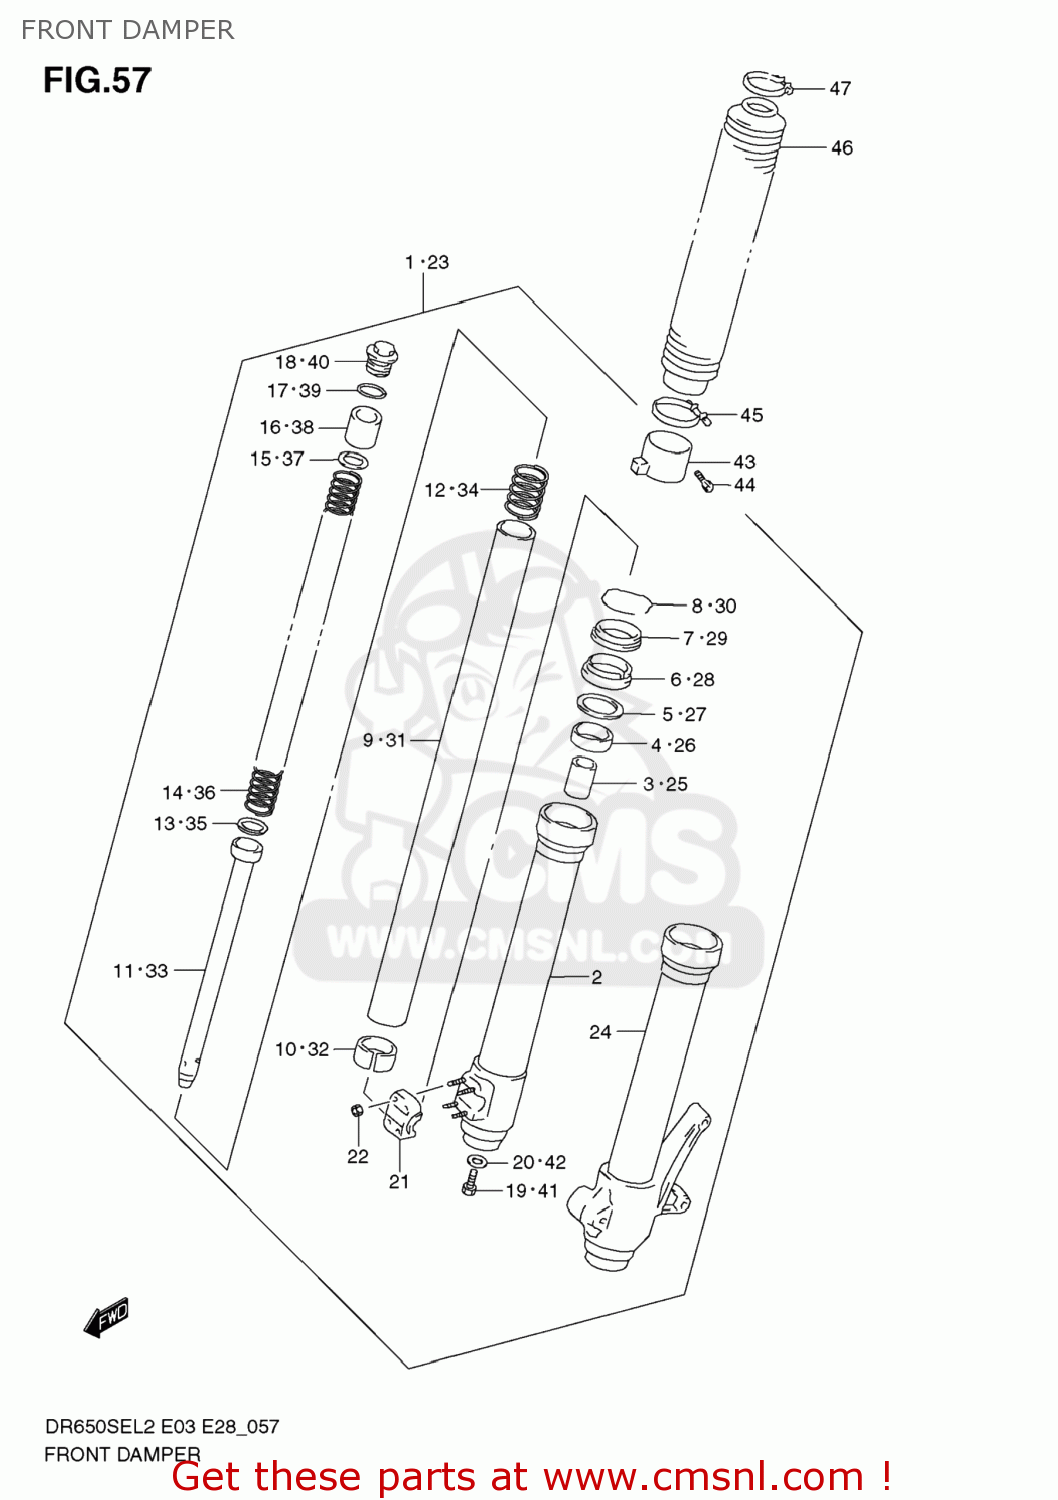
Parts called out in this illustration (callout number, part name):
1	DAMPER ASSY,FR FORK,R
2	TUBE,OUTER,R
3	PIECE,OIL LOCK
4	METAL,SLIDE
5	WASHER
6	SEAL,OIL
7	SEAL,DUST
8	RING,STOPPER
9	TUBE,INNER
10	PISTON
11	CYLINDER
12	SPRING,REBOUND
13	RING,PISTON
14	SPRING
15	WASHER
16	SPACER
17	O RING
18	CAP,FORK
19	BOLT,FORK CYLINDER(10X25)
20	GASKET (NAS)
21	HOLDER,AXLE,R
22	NUT
23	DAMPER ASSY,FR FORK,L
24	TUBE,OUTER,L
25	PIECE,OIL LOCK
26	METAL,SLIDE
27	WASHER
28	SEAL,OIL
29	SEAL,DUST
30	RING,STOPPER
31	TUBE,INNER
32	PISTON
33	CYLINDER
34	SPRING,REBOUND
35	RING,PISTON
36	SPRING
37	WASHER
38	SPACER
39	O RING
40	CAP,FORK
41	BOLT,FORK CYLINDER(10X25)
42	GASKET (NAS)
43	GUIDE,BOOT
44	BOLT
45	BAND,BOOT LWR
46	BOOT, BLACK
47	BAND,BOOT
